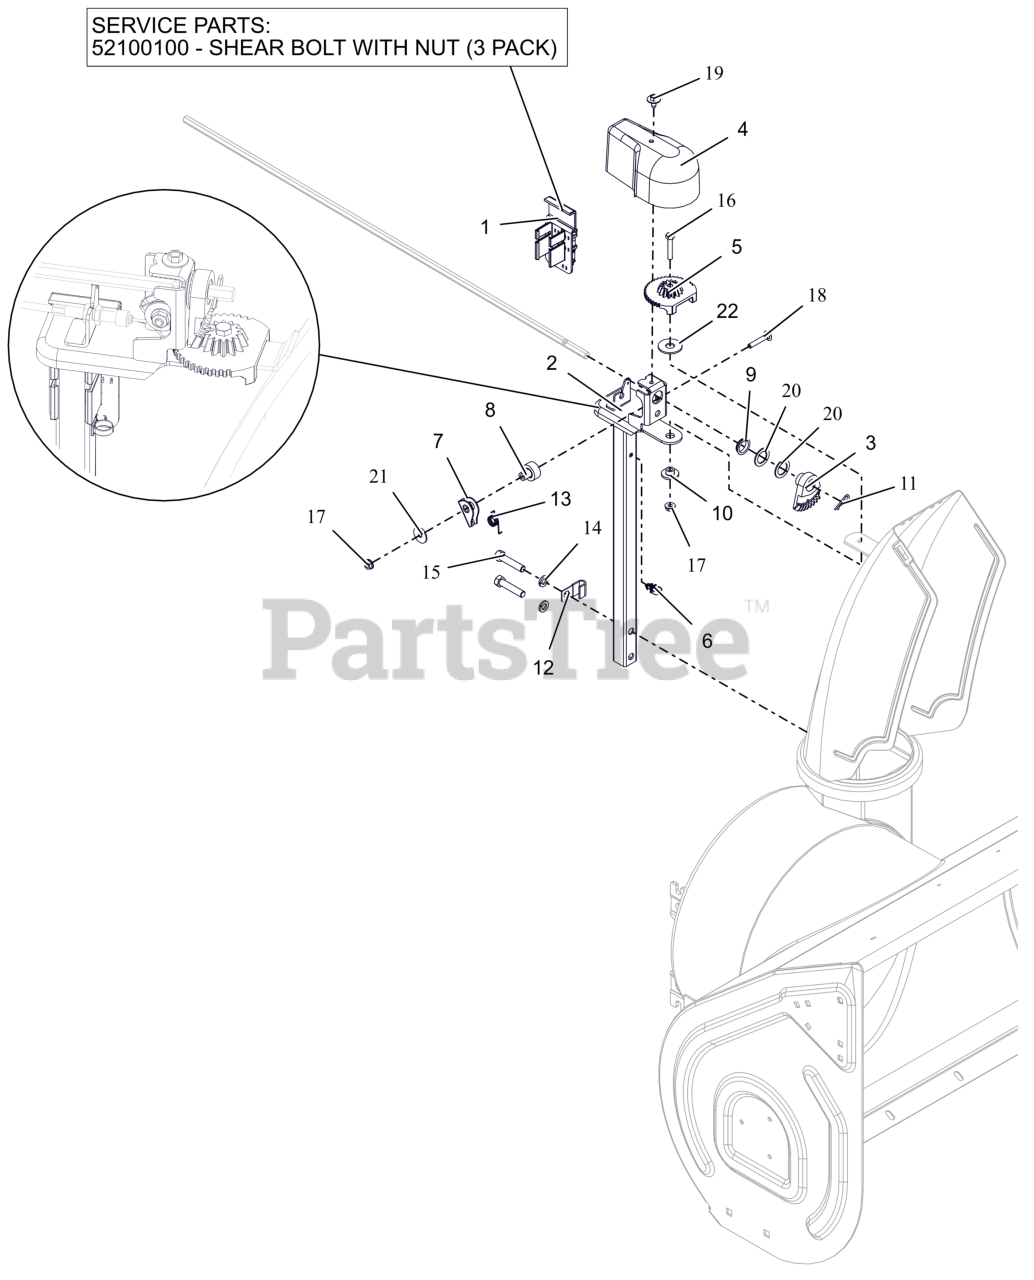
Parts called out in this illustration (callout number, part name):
1	HOLDER W LARGE SHEAR BOLT /NUT
1	SHEAR BOLT SERVICE ASSEMBLY (INCLUDES NUT)
2	PEDESTAL, CHUTE - QUICK STICK
3	GEAR, CHUTE-ACTUATION
4	COVER, CHUTE GEAR
5	GEAR, CHUTE
6	CLIP, CABLE GUIDE
7	ARM, LOCKING
8	BUSHING, LOCK ARM
9	BUSHING, POLYLINER-.75 SNAPIN
10	BSHG-FLG .265X.477X.375X1.00
11	PIN, HAIR #213 .08X1.19 ZCC
12	J-CLAMP
13	SG-TORS
14	WSHR,LK-REG .375X.094 ZCC
15	BLT, HEX .38-16X1.75 G5 ZCC
16	BLT, HEX .25-20X1.50 G5 ZCC
17	NUT-LK-CTR-FLG .25-20 ZC120
18	BLT, RHSN .25-20X1.50 G5 ZCC
19	SCR, TAP .25-20X.50 LG HWH ZCC
20	WSHR, FLT .754X1.125X.062 ZCC
21	WSHR,FLT .281X1.000X.063 ZCC
22	WSHR-FLT-NYL .515X1.375X.093
